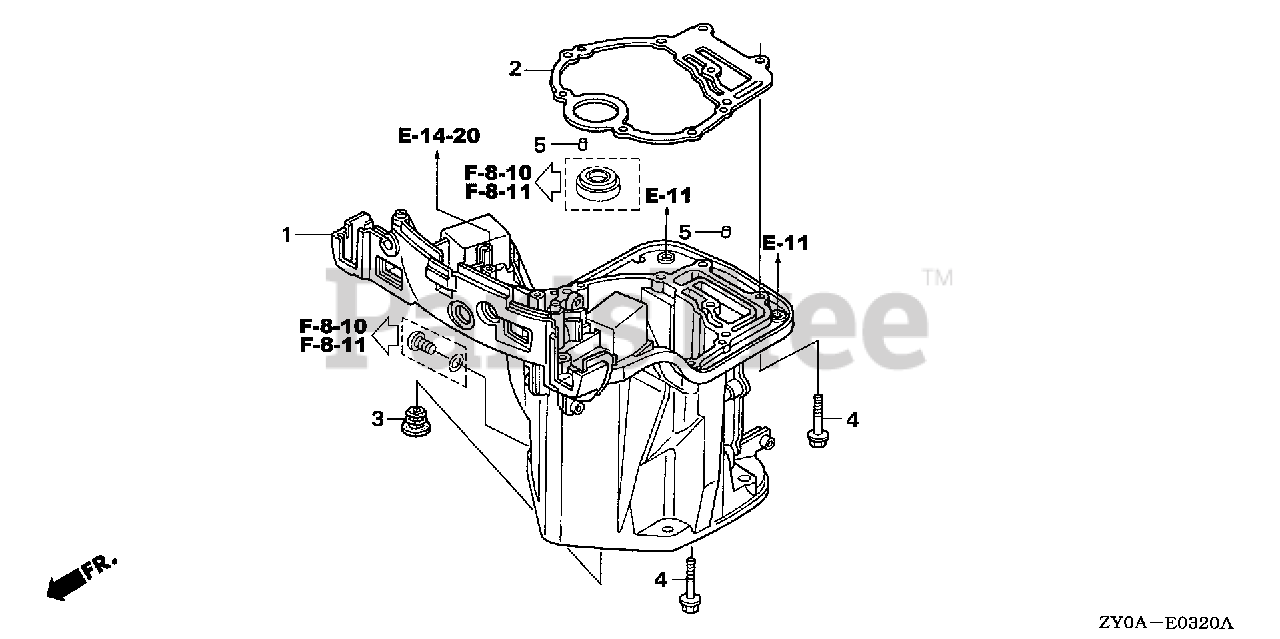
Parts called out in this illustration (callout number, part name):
1	CASE, OIL *NH282MU* (OYSTER SILVER METALLIC-U)
2	GASKET, OIL PAN
3	GROMMET, WATER TUBE
4	BOLT, FLANGE (8X35)
5	PIN, DOWEL (6X10)
